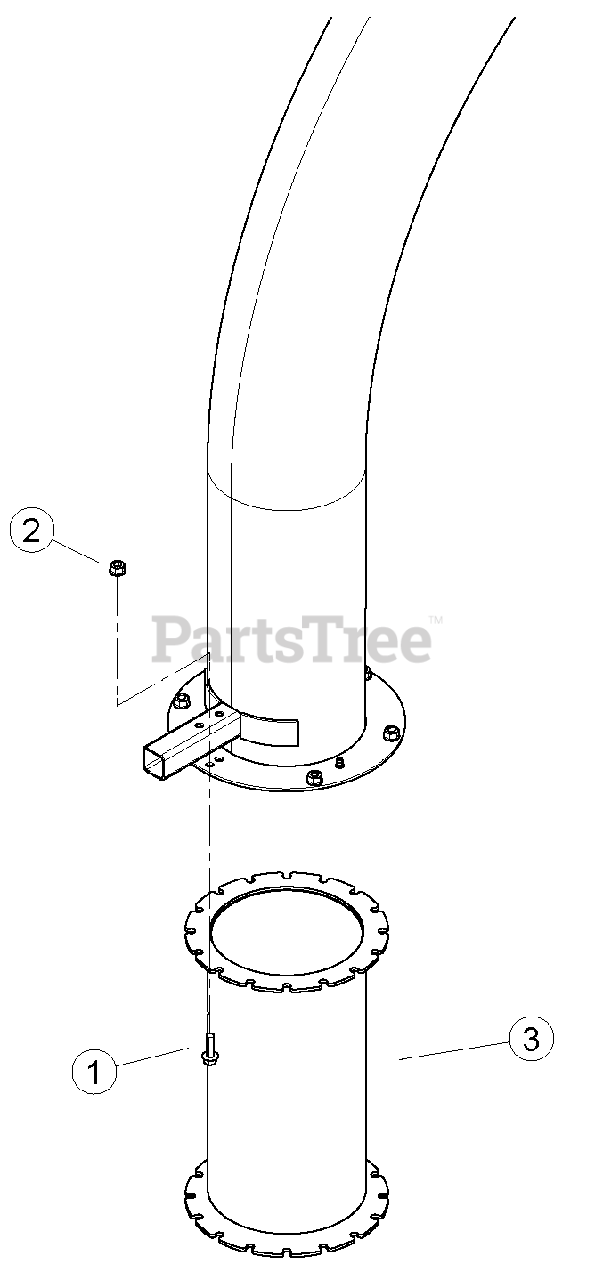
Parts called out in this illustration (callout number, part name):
1	BOLT, 3/8 X 1-1/4 FLANGE NC
2	NUT, 3/8-16 NYLOCK FLANGE
3	WELDMENT, CHUTE EXTENSION
